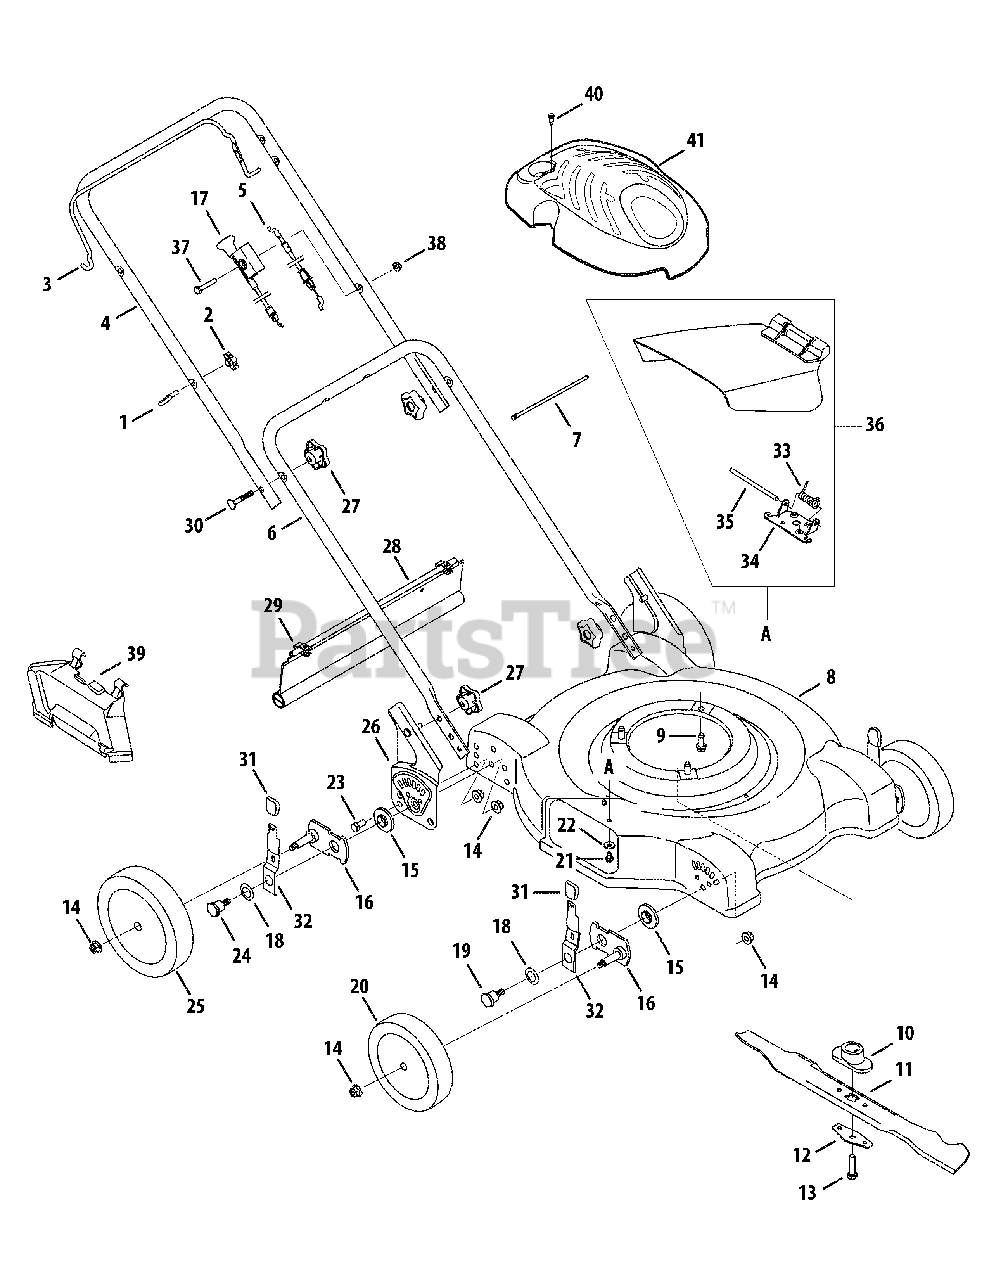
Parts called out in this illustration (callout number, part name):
1	Eye Bolt
2	Wing Nut
5	Conrol Cable
7	Cable Tie
9	TT Screw, 3/8-16 x 1.0
10	Blade Adapter
11	Standard Blade, 22''
11	Mulching Blade, 22''
12	Blade Bell Support
13	Screw, 3/8-24 x 1.5
14	Lock Nut, 3/8-16
15	Height Adjuster Bearing
16	Pivot Arm
17	Choke Cable
18	Bell Washer, .760 OD x 1.25 OD
19	Shoulder Screw
20	Front Wheel, 7 x 1.8, Bar
21	TT Screw, 1/4-20 x .5
22	Bell Washer, .265 ID x .75 OD
23	Screw, 3/8-16 x .75
24	Shoulder Screw
25	Rear Wheel, 8 x 1.8, Bar
27	Star Knob
28	Trailshield
29	Hinge Clip
30	Carraige Bolt, 5/16-18 x 2
31	Knob
32	Lever
33	Torsion Spring
34	Chute Hinge
35	Hinge Pin
36	Hinged Chute Deflector Assembly
37	Screw, 1/4-20 x 1.50
38	Flange Lock Nut, 1/4-20
39	Mulching Baffle
40	Machine Screw, M4-.7
41	Engine Shroud
